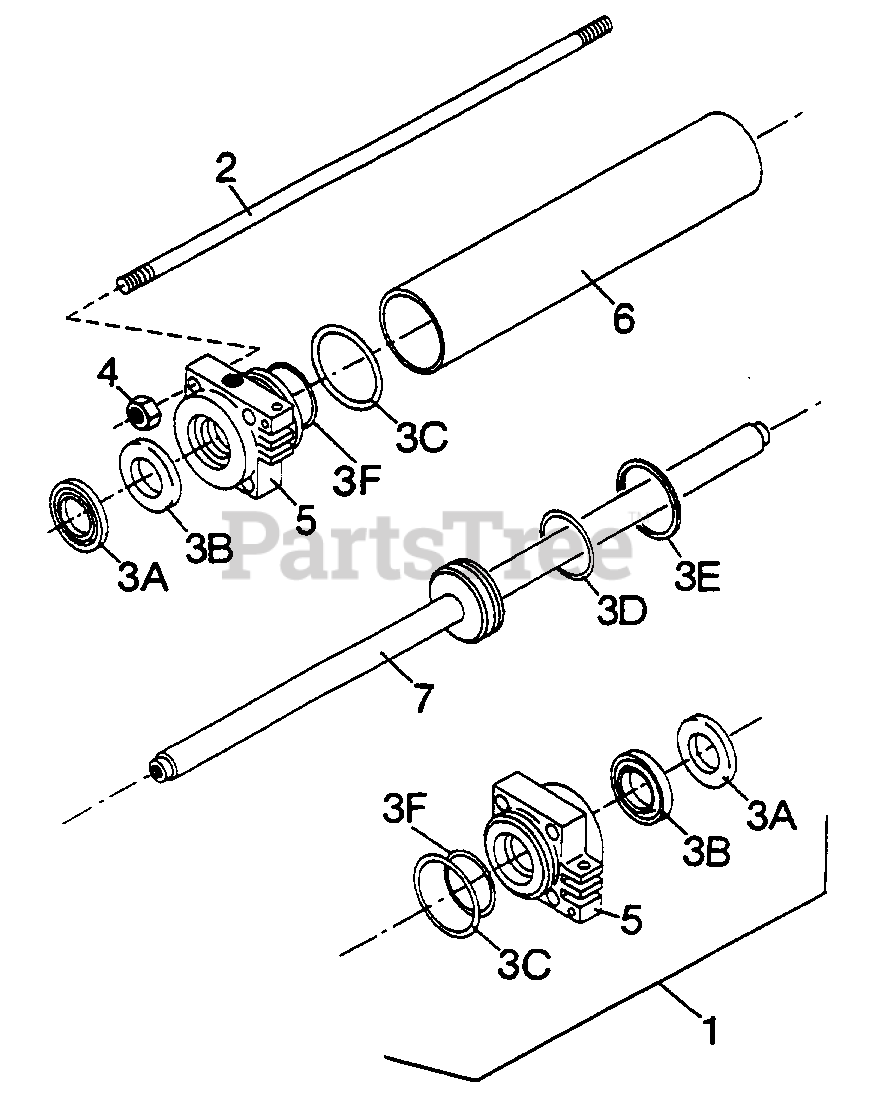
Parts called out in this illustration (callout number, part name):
1	Hydraulic swing cylinder complete
2	7/16 NF x 16 Tie rod
3A	Rod wiper
3B	Rod seal
3C	Gland static seal
3D	O-Ring
3E	Piston seal
3F	Back-up ring
4	7/16 NF Hex nut
5	Piston rod guide
7	Rod assembly
